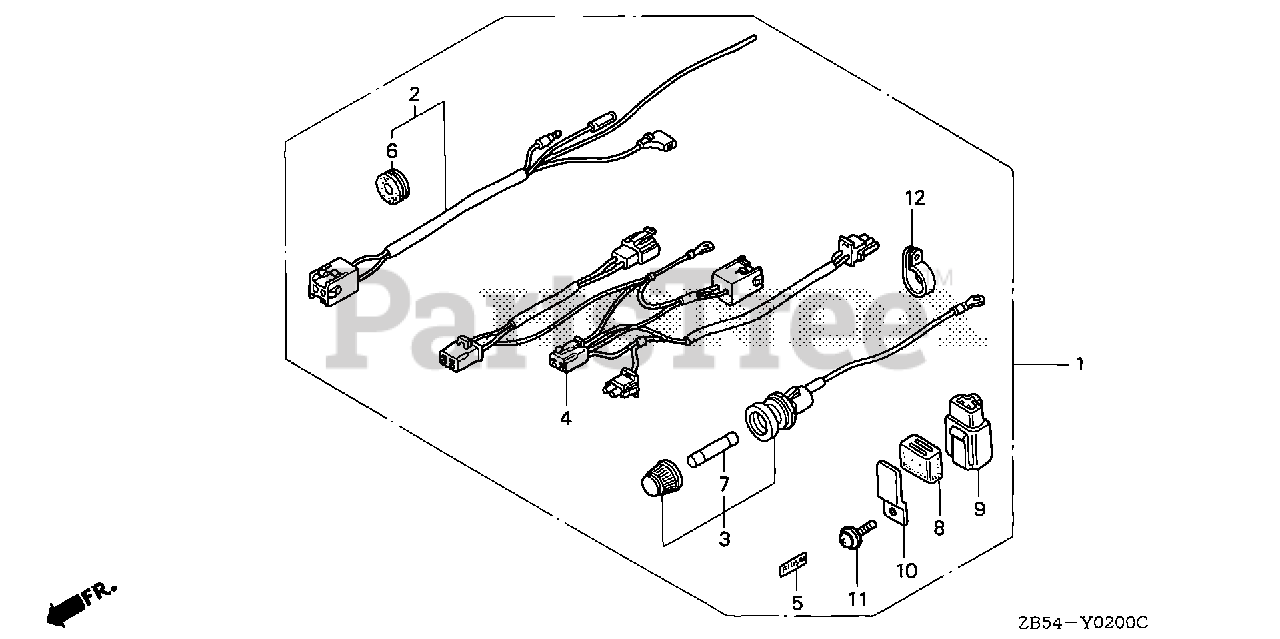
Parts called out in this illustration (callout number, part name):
1	HARNESS KIT
2	HARNESS ASSY., BOX
3	HOLDER ASSY., FUSE
4	HARNESS ASSY., GENERATOR
5	MARK, FUSE CAPACITY
6	RUBBER B, RADIATOR CAP MOUNTING
7	FUSE (15A)
8	SUSPENSION, TURN SIGNAL RELAY (MITSUBA)
9	RELAY, CONTROL
10	BRACKET, RELAY
11	SCREW, TAPPING (5X12) (GROUND CABLE)
12	CLIP (10.7MM)
